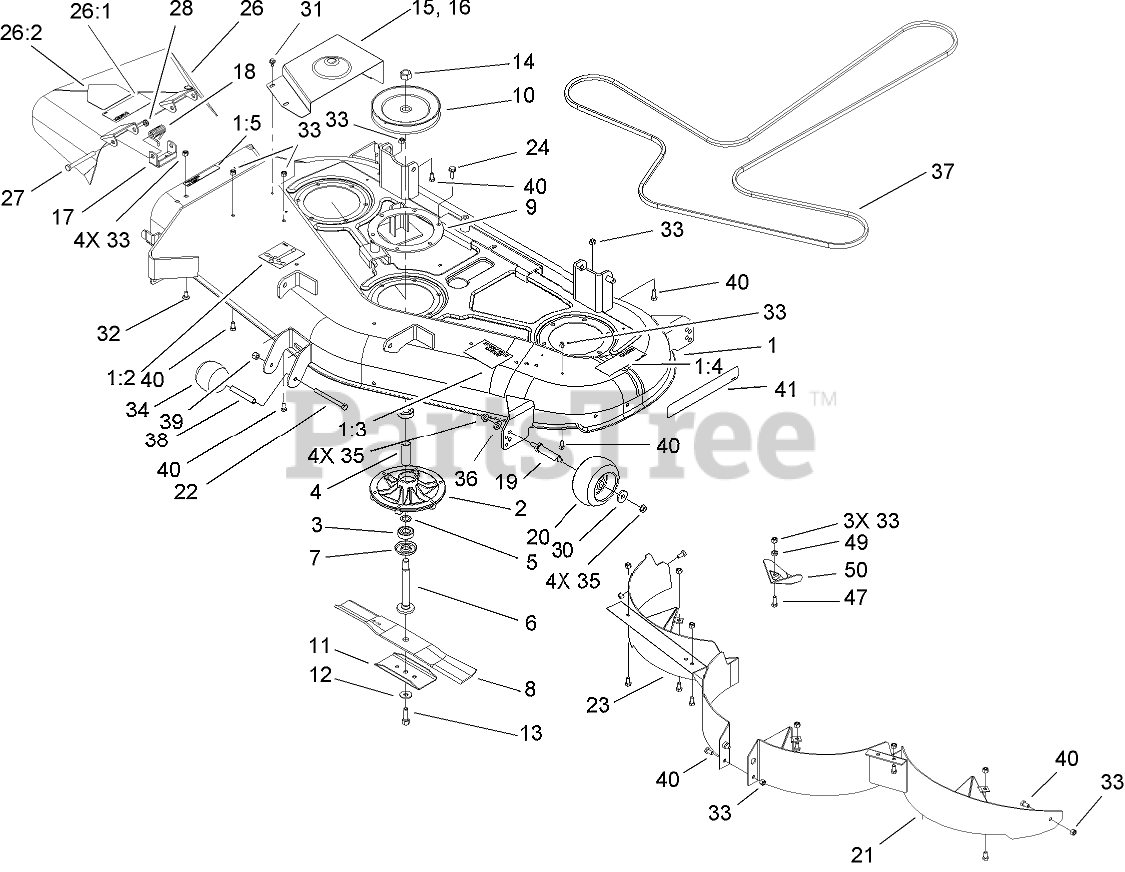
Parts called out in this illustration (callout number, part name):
1	Deck ASM
1:2	DECAL-ROUTING, BELT
1:3	DECAL-ANTI SCALP
1:4	DECAL-DANGER
1:5	DECAL-DANGER
2	HOUSING-SPINDLE
3	BEARING-BALL
4	SPACER
5	SPACER
6	SHAFT-SPINDLE
7	SHIELD-BEARING
8	BLADE-RECYCLER
9	RING-SUPPORT, DECK
10	PULLEY AND HUB ASM
11	STIFFENER-BLADE
12	WASHER-BELLEVILLE
13	SCREW-HH
14	NUT-HEX
15	COVER-BELT, LH
16	COVER-BELT, RH
17	BRACKET-PIVOT
18	SPRING
19	SPACER
20	WHEEL-GAGE
21	LEFT BAFFLE ASM
22	SCREW-HH
23	RIGHT BAFFLE ASM
24	SCREW-TAPTITE
26	DEFLECTOR ASM
26:1	DECAL-DANGER
26:2	DECAL-DANGER
27	SCREW-HH
28	NUT-HEX
30	WASHER
31	SCREW-HHFTF
32	SCREW-CARR
33	NUT-LOCK, NI
34	ROLLER
35	NUT-HHF, WHIZ
36	WASHER-BELLEVILLE
37	BELT-V
38	TUBE-SPACER, WHEEL
39	NUT-LOCK, NI
40	SCREW-HH
41	Decal-Deck
47	SCREW-HH
49	SPACER
50	PLATE-KICKER
